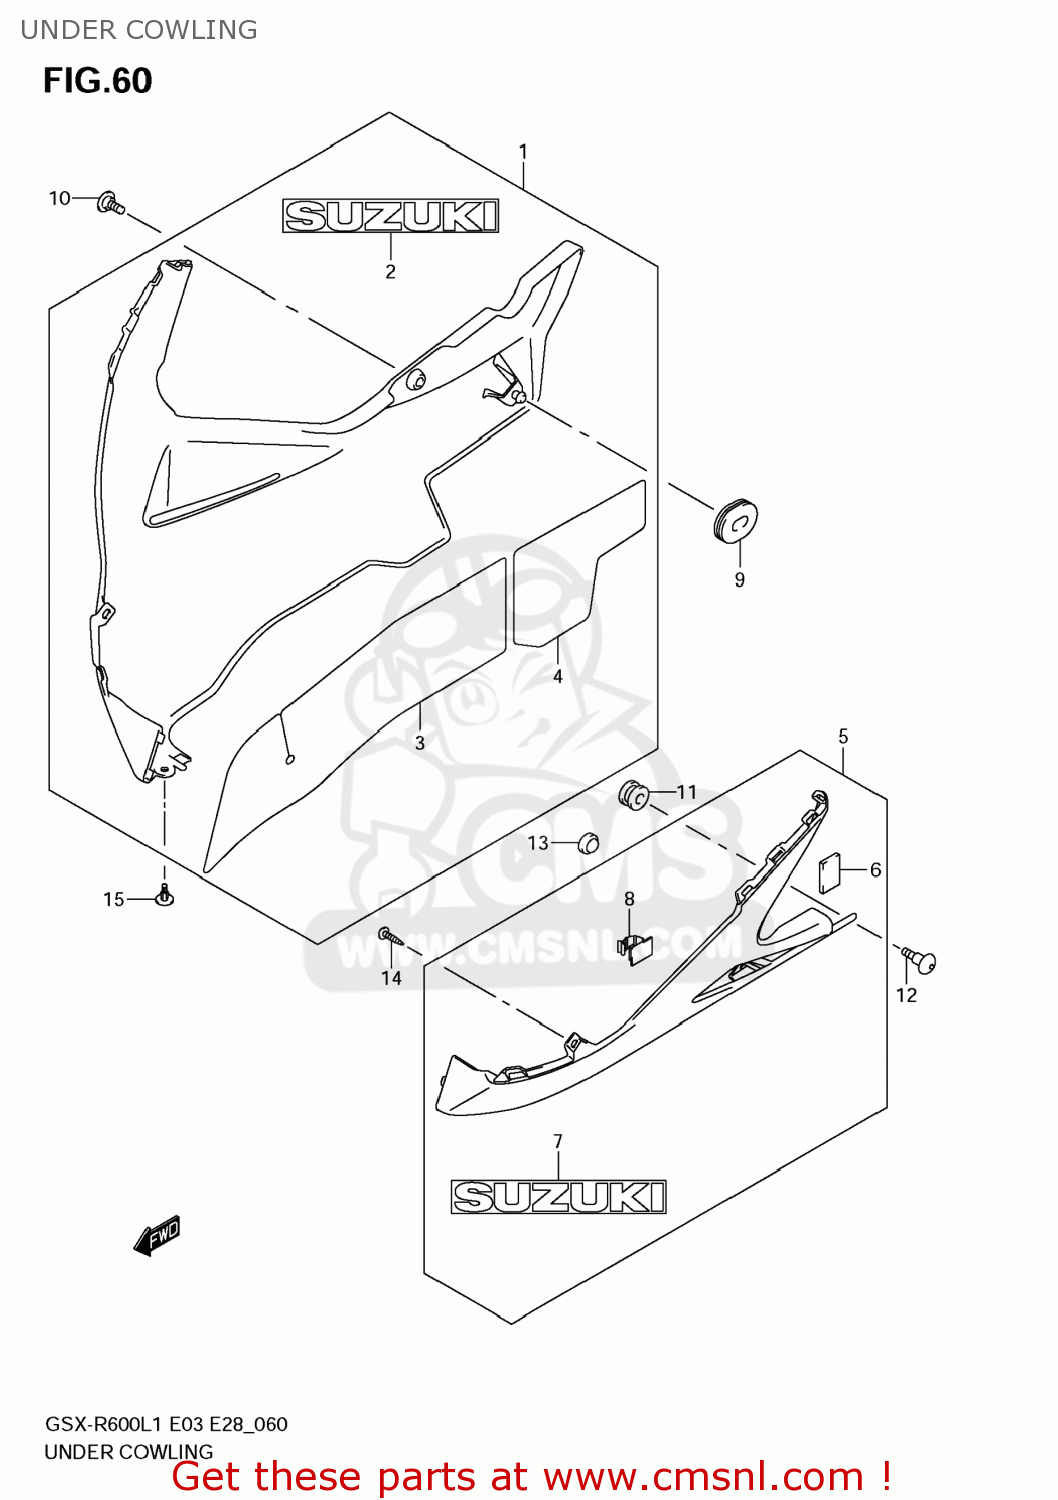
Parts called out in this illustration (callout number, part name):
1	COWLING,UNDER,R(WHITE)
2	EMBLEM,SUZUKI
3	SHIELD,UNDER COWL HEAT,R
4	SHIELD,UNDER COWL HEAT,R
5	COWLING,UNDER,L(WHITE)
6	CUSHION,BRACKET NO.1
7	EMBLEM,SUZUKI
8	CLAMP
9	CUSHION,UNDER COWLING,R
10	SCREW(5X13)
11	CUSHION
12	BOLT(6X20)
13	CUSHION
14	SCREW
15	CLIP
